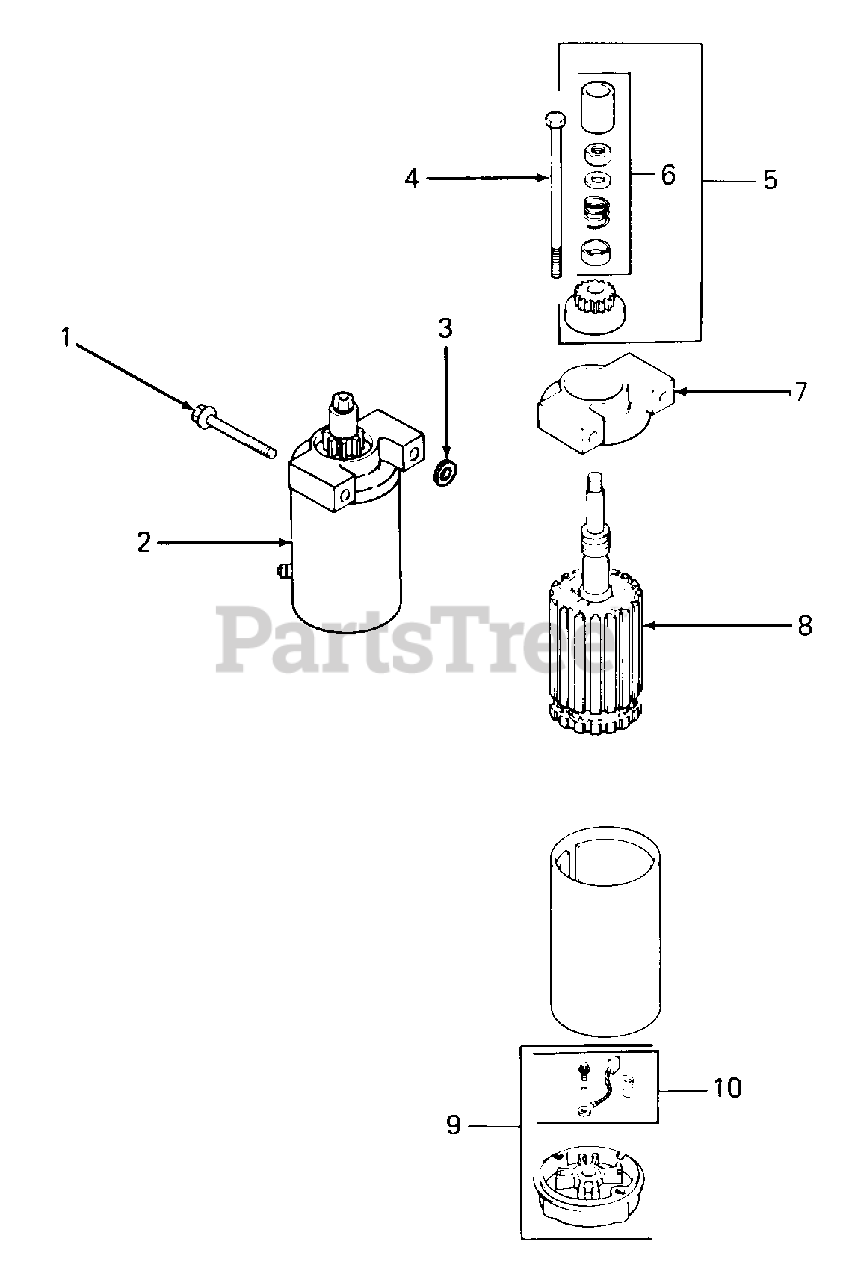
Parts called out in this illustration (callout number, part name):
1	Screw, Bendix Starter, M8 X 1.25 X 65.5
2	Starter, Bendix Assy
3	Washer, Flat
4	Screw, Hex Flange, 1/4-20 X 4-1/4
5	Kit, Drive
6	Kit, Drive Parts
7	Cap, Drive End
9	Cap, Commutator End Assy
10	Kit, Brush
